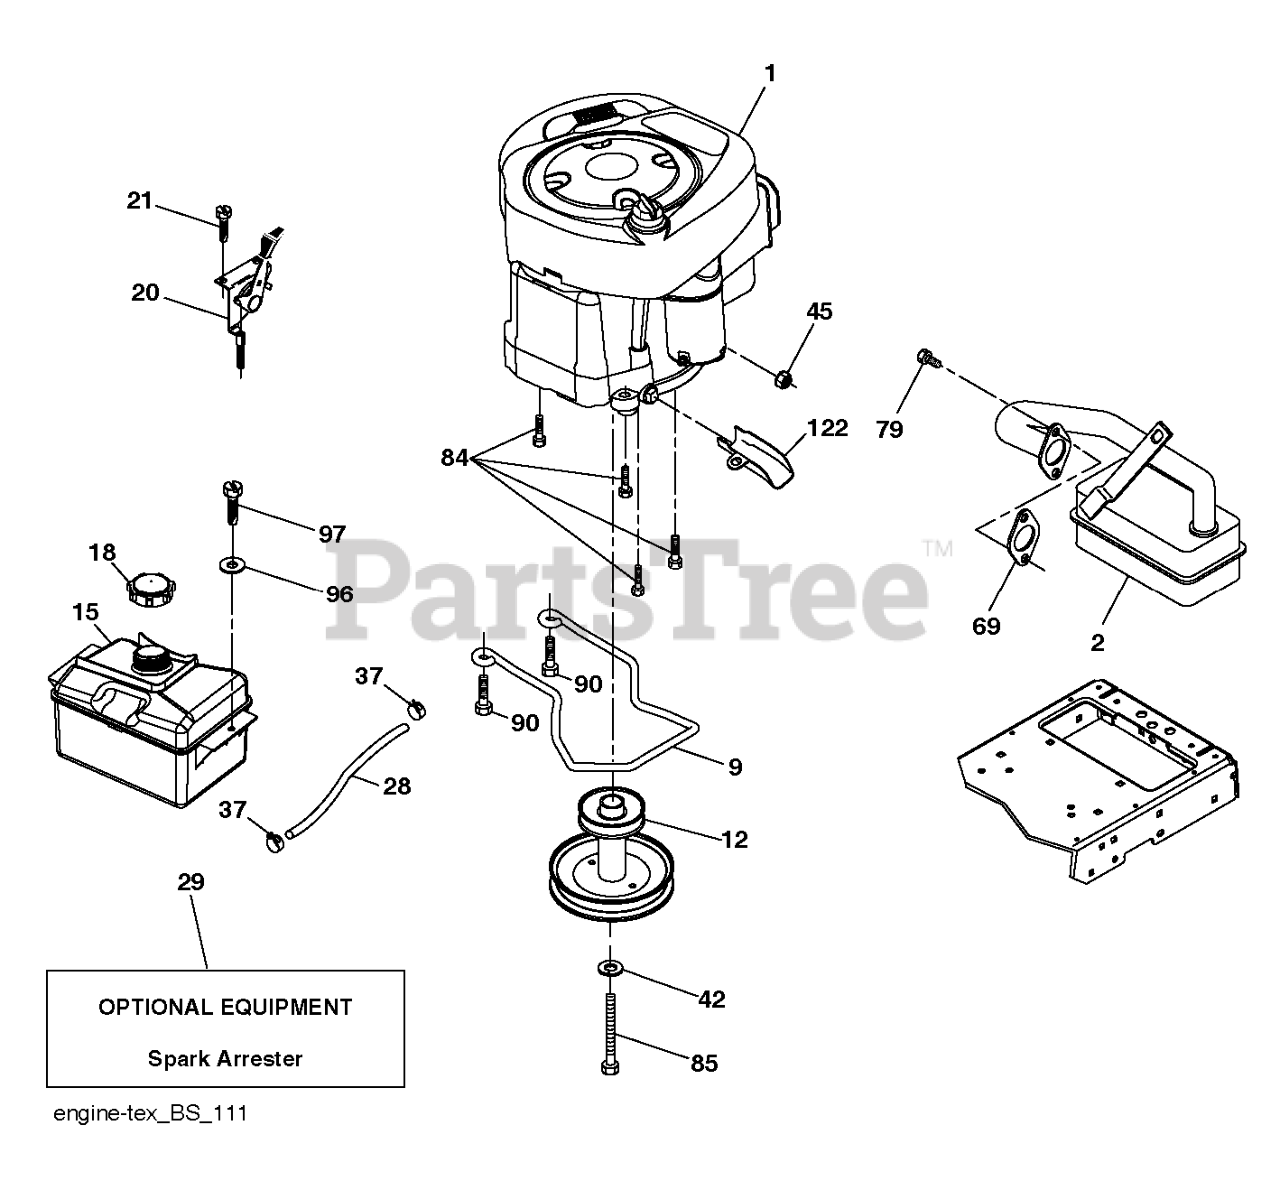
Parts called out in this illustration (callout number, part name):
2	MUFFLER.LT.BRIGGS.14HP.IC/OHV
9	KEEPER.BELT.ENG.4.25"2.BLT.431
12	ENGINE.PULLEY
15	FUEL.TANK.ASM.NON-EPA
18	CAP ASM.FUEL.2.25"FR.
20	THROTTLE.COBRA.21".RSTART.BLK
28	LINE.FUEL.20
29	KIT.SPARK ARRESTOR 794945 B&S
37	HOSE CLAMP
69	REPL BY 532 27 22-93
84	SCREW.3/8-16
85	BOLT.HEX.7/16-20X4.GR5.1.5BLUE
90	SCREW 3/8-16X1
97	SCREW HEXWSHR 1/4-20X3/4
122	EXTENSION DRAIN OIL
